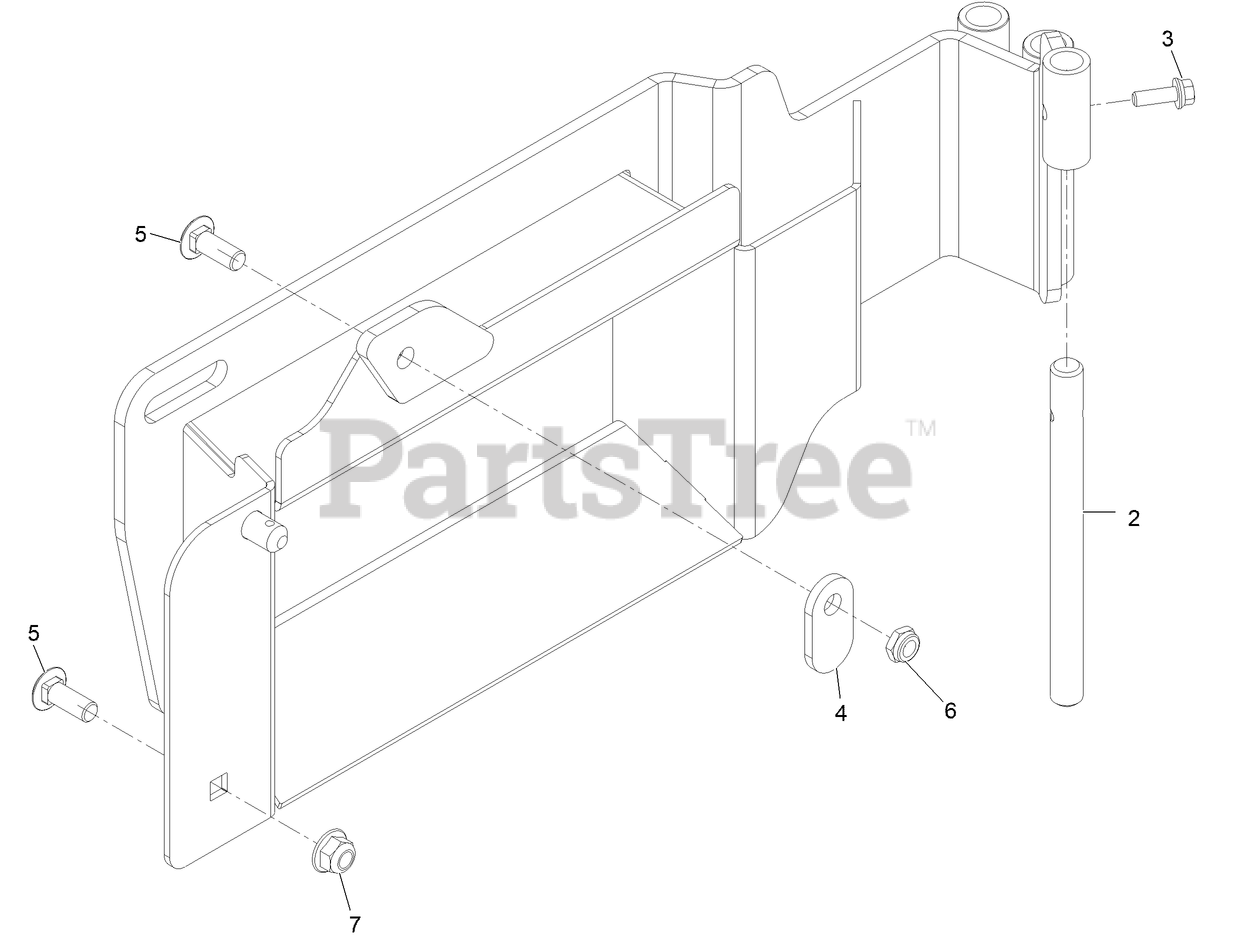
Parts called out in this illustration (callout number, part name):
2	PIN-MOUNT, OCD
3	SCREW-HHF
5	SCREW-CARR
7	NUT-HF, NI
